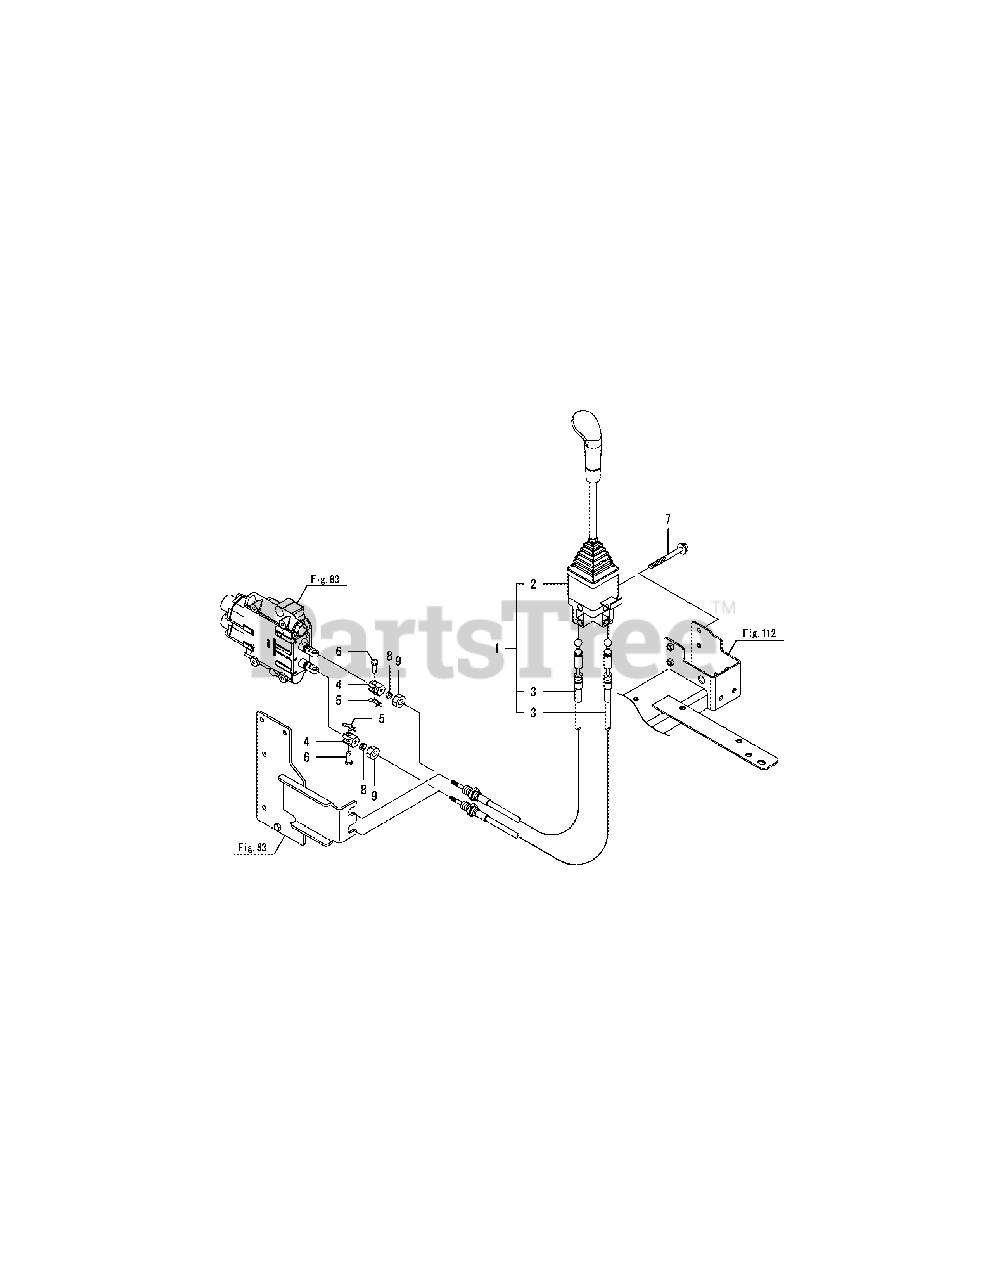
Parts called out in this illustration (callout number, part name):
3	WIRE, JOYSTICK
5	PIN 8, COME-OFF SNAP
7	BOLT M 8X 85 PLATED
9	LOCK NUT M16 PLATED
